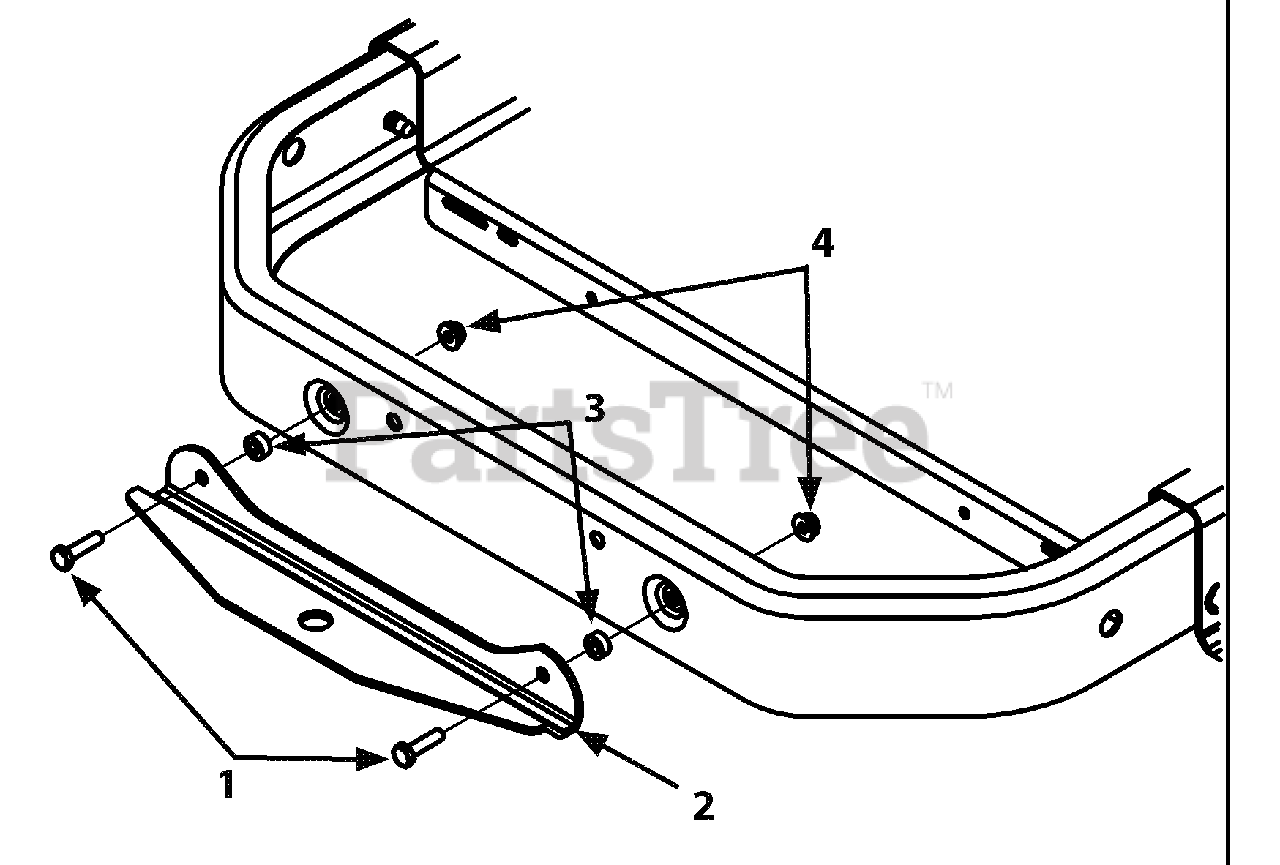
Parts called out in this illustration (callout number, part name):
1	Hex Screws, 1/4-20 X1.00
2	Hitch Bracket
3	Spacers .256X.500X.240LG
4	Flange Lock Nuts 1/4-20
